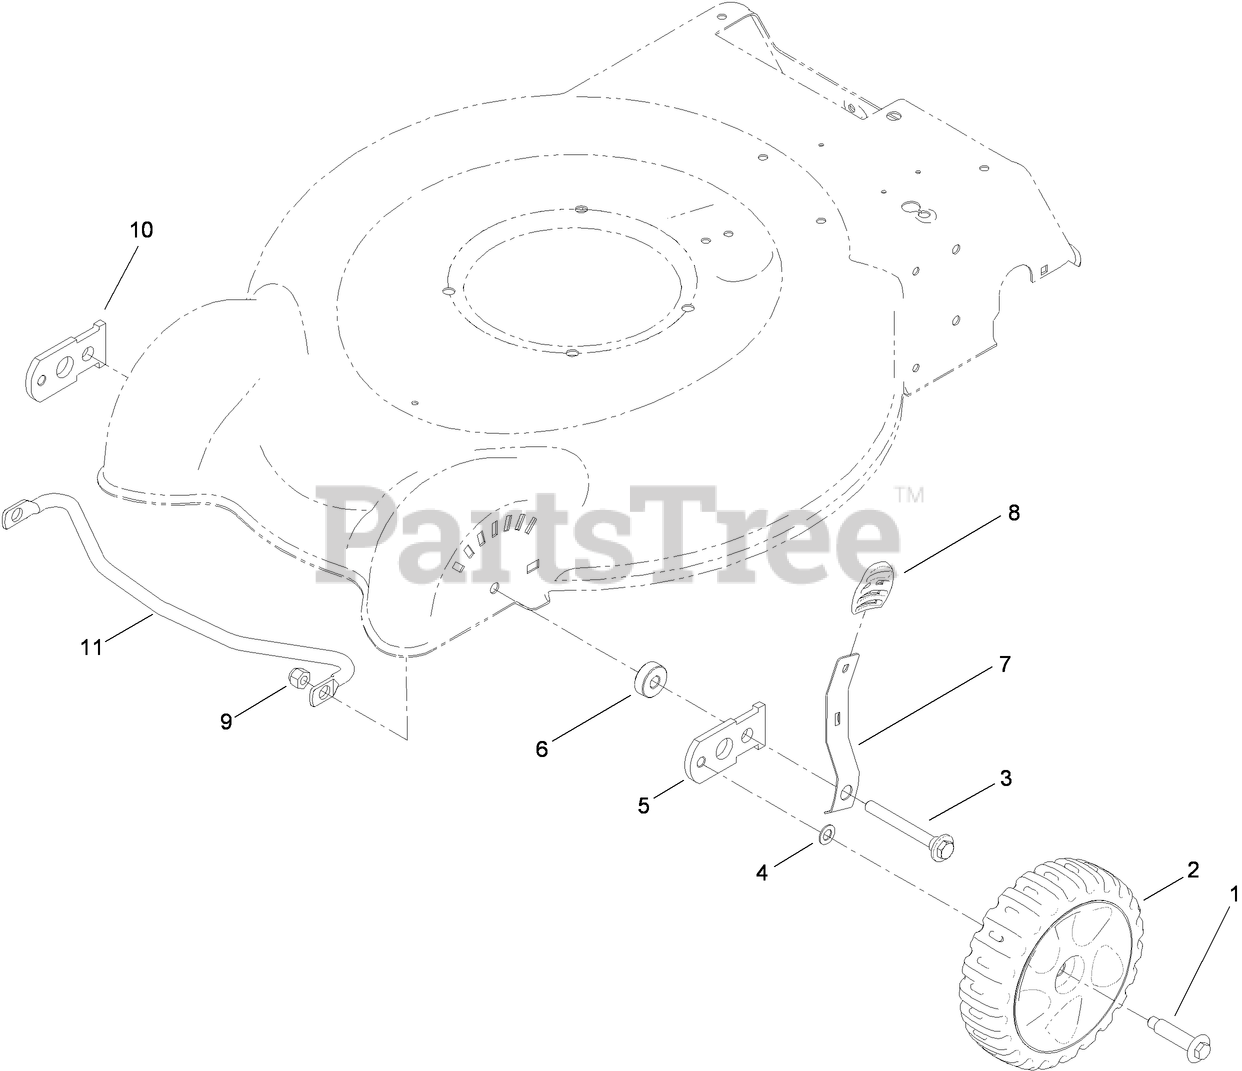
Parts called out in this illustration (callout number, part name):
1	BOLT-SHOULDER
2	7 INCH WHEEL AND TIRE ASM
3	SCREW-SHOULDER, HWH
4	WASHER
5	ARM-PIVOT, RH
6	SPACER-ARM, PIVOT
7	ARM-SPRING, FRONT
8	KNOB-LEVER, HOC
9	NUT-LOCK, NI
10	ARM-PIVOT, LH
11	BRACE-FRONT
